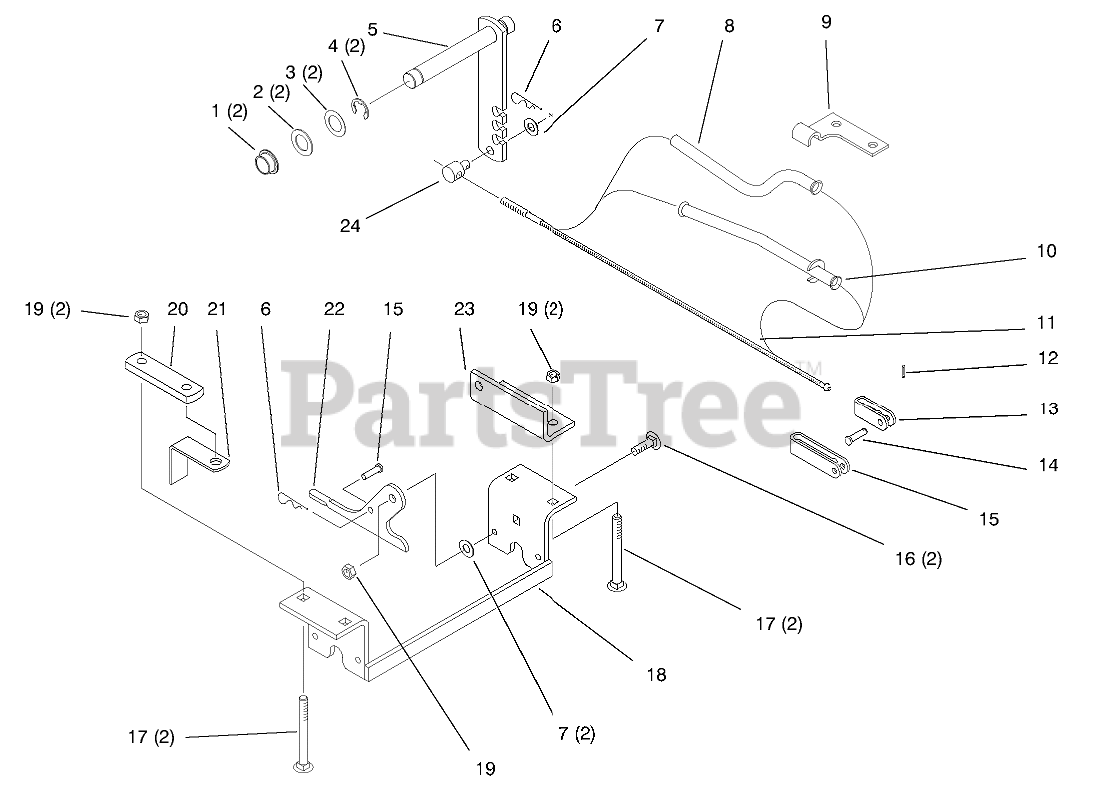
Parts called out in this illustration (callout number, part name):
1	BUSHING-BRONZE
2	WASHER
3	WASHER-SHIM
4	E-RING
5	ASSY LEVER R
6	PIN-HAIR
7	WASHER-FLAT
8	TUBE-CONDUIT R
9	CLAMP-CONDUIT R
10	TUBE ASSY COMPLET R
11	CABLE
12	PIN-COTTER
13	CLEVIS-SHORT
14	PIN-CLEVIS
15	CLEVIS-LONG
16	BOLT-CARR
17	SCREW-CARR
18	Bracket
19	NUT-HEX
20	BRACKET-REAR LINK MOUNTING
21	SPACER-BRACKET
22	PLATE-LATCHING
23	LINK-BRACKET R
24	TRUNNION-CLUTCH ROD
